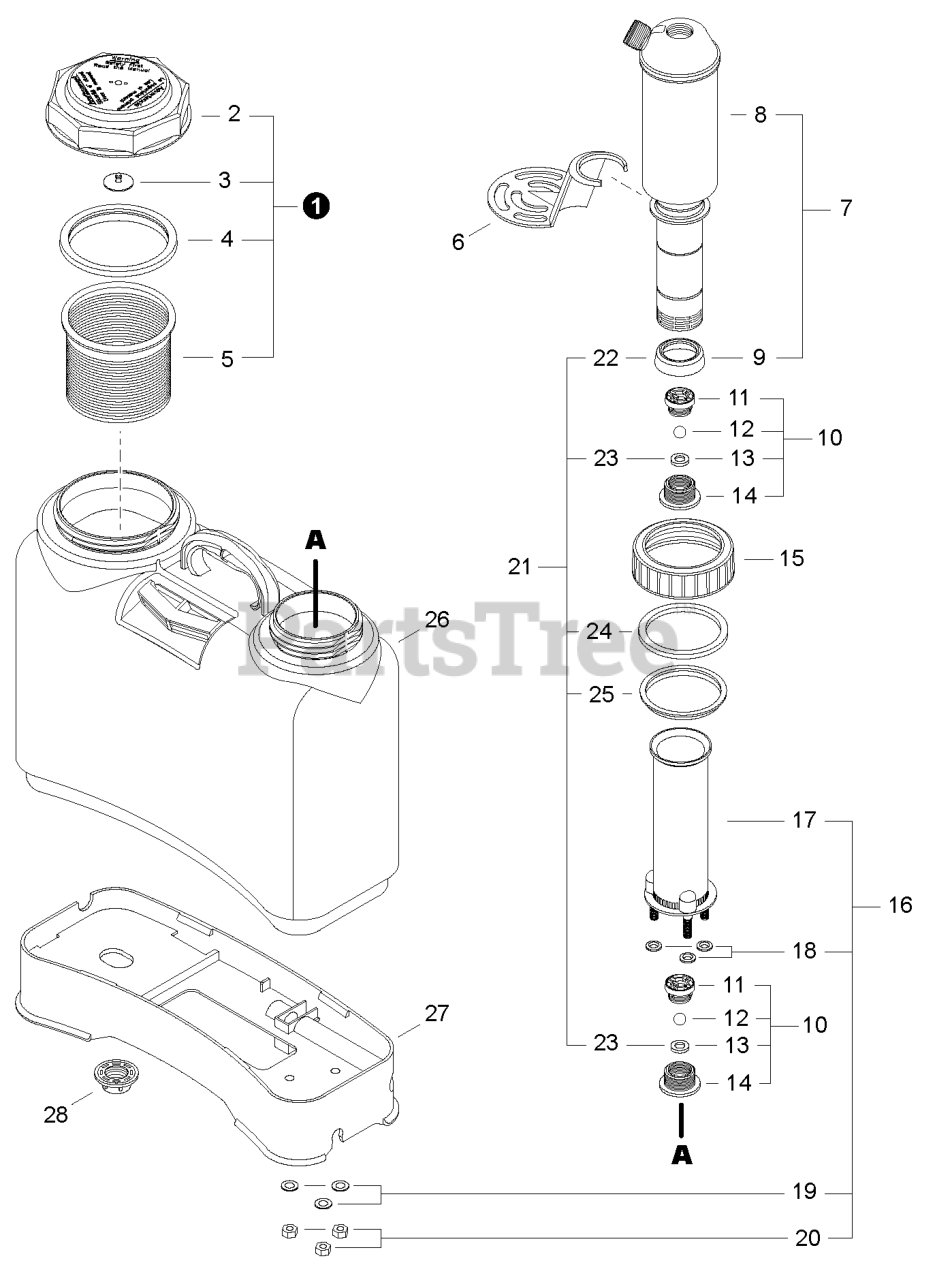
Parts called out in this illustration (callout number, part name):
1	TANK CAP KIT
2	CAP, TANK
3	VALVE, CHECK - CAP
4	GASKET, BASKET
5	BASKET, FILTER
6	AGITATOR
7	PRESSURE CHAMBER KIT
8	CHAMBER, PRESSURE
9	CUP, PLUNGER
10	CHECK VALVE ASSY
11	BODY, VALVE
12	VALVE, BALL
13	WASHER
15	RING, LOCKING
16	CYLINDER/PISTON KIT
17	CYLINDER
18	GASKET, STUD
19	WASHER
21	PUMP GASKET KIT
22	CUP, PLUNGER
23	WASHER
24	WASHER - FELT
25	GASKET, CHAMBER
26	TANK, SPRAYER
27	BASE, TANK
28	NUT, TANK
